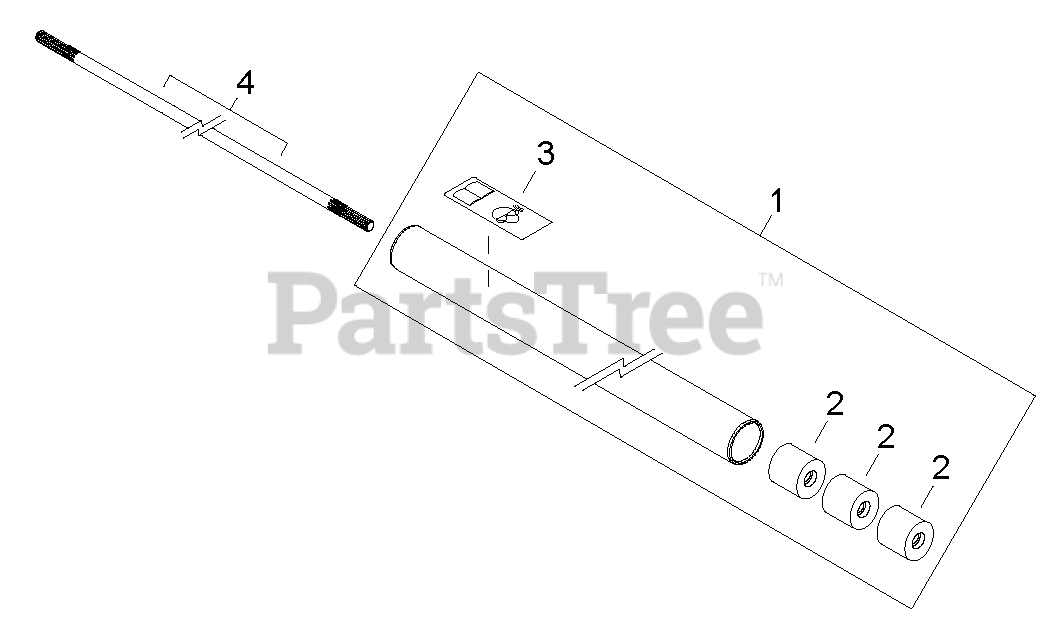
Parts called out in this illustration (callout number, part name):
2	BUSHING
3	LABEL - CAUTION
4	PIPE, MAIN
9-1	MAIN PIPE ASSY
